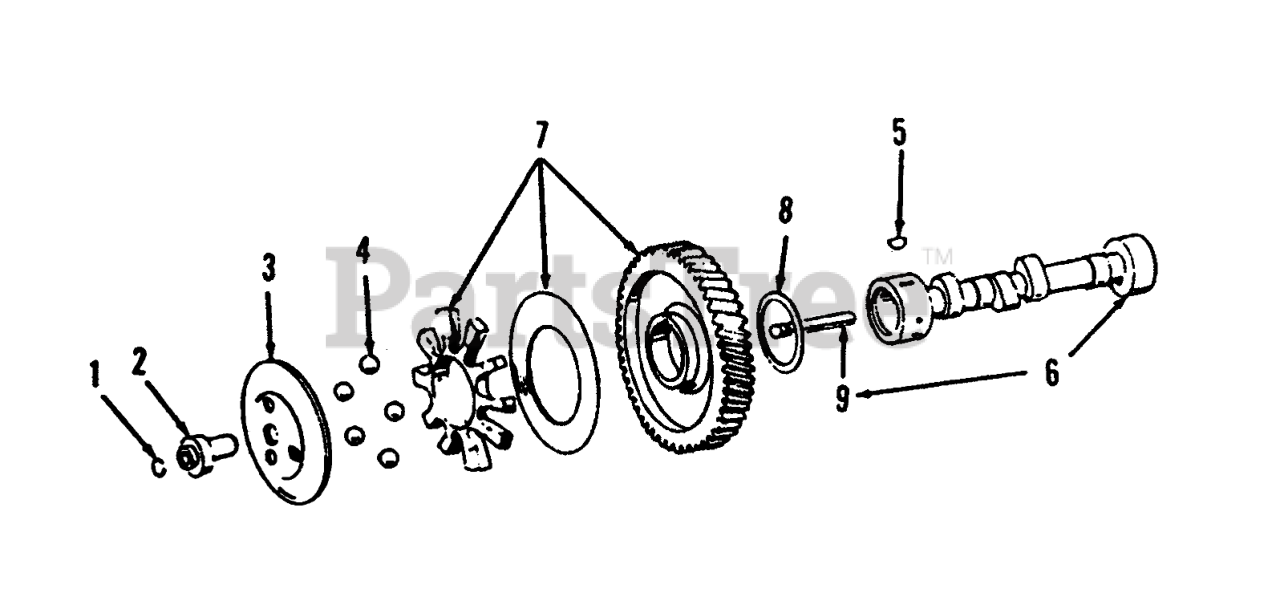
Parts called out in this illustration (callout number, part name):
2	HUB-GOVERNOR CUP
3	CUP-GOVERNOR
4	Ball
6	Camshaft (Includes Center Pin)
7	Gear-Camshaft (Includes Gear, Spacer, & Plate)
8	Washer
9	Pin
